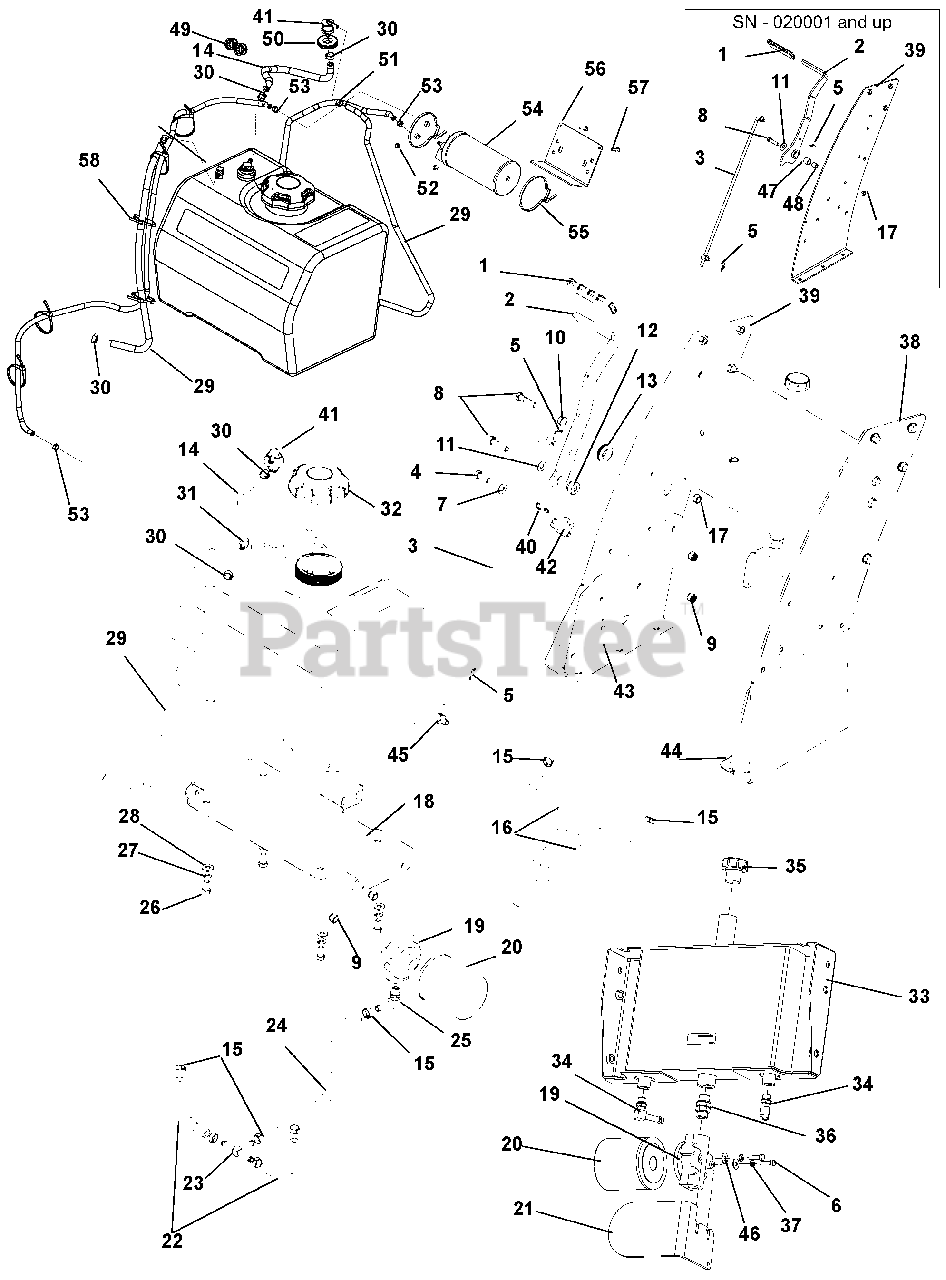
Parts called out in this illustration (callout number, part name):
1	GRIP, PVC .250 X 1.00 X 3.63
2	LEVER, HAND BRAKE FLOAT WALK (SN 000101 - 020000)
3	ROD, DRIVE CONTROL FW
4	BOLT, HEX .38-16 X 1.00
5	RING, RUE .375 X .054 X 1.254
6	BOLT, HEX .25-20 X 1.00 GR5 Y (SN 000101 - 020000)
7	WASHER, FL-STL .406 X .812 X .065
8	BOLT, HEX .38-16X1.50 GR5 Y
9	NUT-LOCKING-NYLON .38-16
10	NUT-SPNLK-FLG .375-16
11	WASHER-FL-STL .38 X .875 X .083
12	BUSHING, BRAKE LEVER STAND OFF
13	GROMMET: RUB:.88ID X 1.38OD X .14GR
14	HOSE, FUEL HYDRO TANK - ROV
15	CLAMP, HOSE - 1/2" PINCH
16	HOSE, HYD .375 X 10 (SN 000101 - 020000)
17	NUT, LK-CTR .38-16
18	BRACKET, FUEL TANK RMHF (SN 000101 - 010000)
19	HEAD, OIL FILTER
20	FILTER, OIL
21	GUARD, HYDRO FILTER FLWLK (SN 000101 - 010000)
22	HOSE, HYD 3/8 X 6.00
23	FTG, TUN 3/8 HOSE
24	HOSE, HYD. .375 X 12
25	FTG, 90 BRB-OR 4601-06-08
26	BOLT, HEX .38-16 X .75 GR5 Y
27	WASHER, LK .38 X .094 REG
28	WASHER, FL-STL .406 X .812 X .065
29	HOSE, FUEL 1/4 X 15.00
30	CLAMP, FUEL LINE
31	TANK, FUEL (SN 000101 - 021000)
32	CAP, FUEL NONVENT, AUTOLOCK
33	WLDT, TANK (SN 000101 - 020000)
34	FTG, 90 9/16 MOR X 3/8 HOSE (SN 000101 - 020000)
35	CAP, OIL FILL BREATHER
36	STRAIGHT UNION SAE 8
37	WASHER, LK .25 X .062 REG
38	WLDT, LH UPRIGHT TOWER 36 (SN 000101 - 010000) (988153)
39	WLDT, RH UPRIGHT TOWER 36 (SN 000101 - 010000) (988153)
40	SCREW, 10-24 X .75 HWH
41	VALVE, COMBINATION (988156)
42	SWITCH- DOUBLE POLE N.O./N.O.
43	PLATE, DOUBLE RH UPRIGHT BI (SN 000101 - 010000)
44	PLATE, DOUBLE LH UPRIGHT BI (SN 000101 - 010000)
45	SWIVEL, 3/8-24
46	WASHER-FLAT-STL .312 X .734 X .065
47	PARK BRAKE LEVER BUSHING (SN 021000 and up)
48	PARK BRAKE LEVER SPACER (SN 021000 and up)
49	BUSH, PANEL SNAP .687X.875X.56 (988153)
50	GROMMET, REMOTE ROV (988153)
51	CLAMP, DBL PINCH 5/16" - 7/16" (988153)
52	NUT-KEPS 10-24 (988153) (SN 021000 and up)
53	CLAMP - HOSE, SPRING .188 (988153)
54	400 CC CARBON CANISTER 3/16 PT (988153)
55	CABLE TIE, .19 X 14.4 (988153)
56	BRKT, CARB CANISTER MTG (988153)
57	SCR-MCH 10-24X.75 HWH YWZC (988153)
58	CABLE TIE, .15 X 8.50 (988153)
